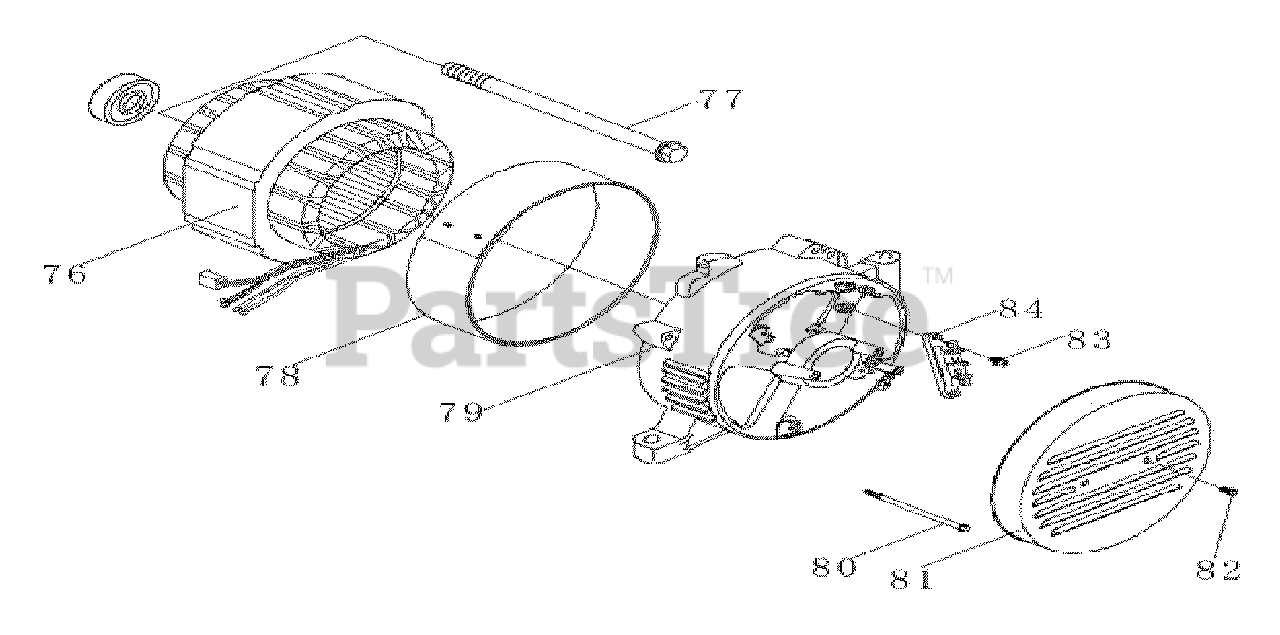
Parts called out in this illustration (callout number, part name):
78	Stator cover
79	Rear frame
80	M6 x 175 Bolt
81	Rear cover
82	M5 x 12 flanged bolt
83	M5 x 12 flanged bolt
84	Wire rack
